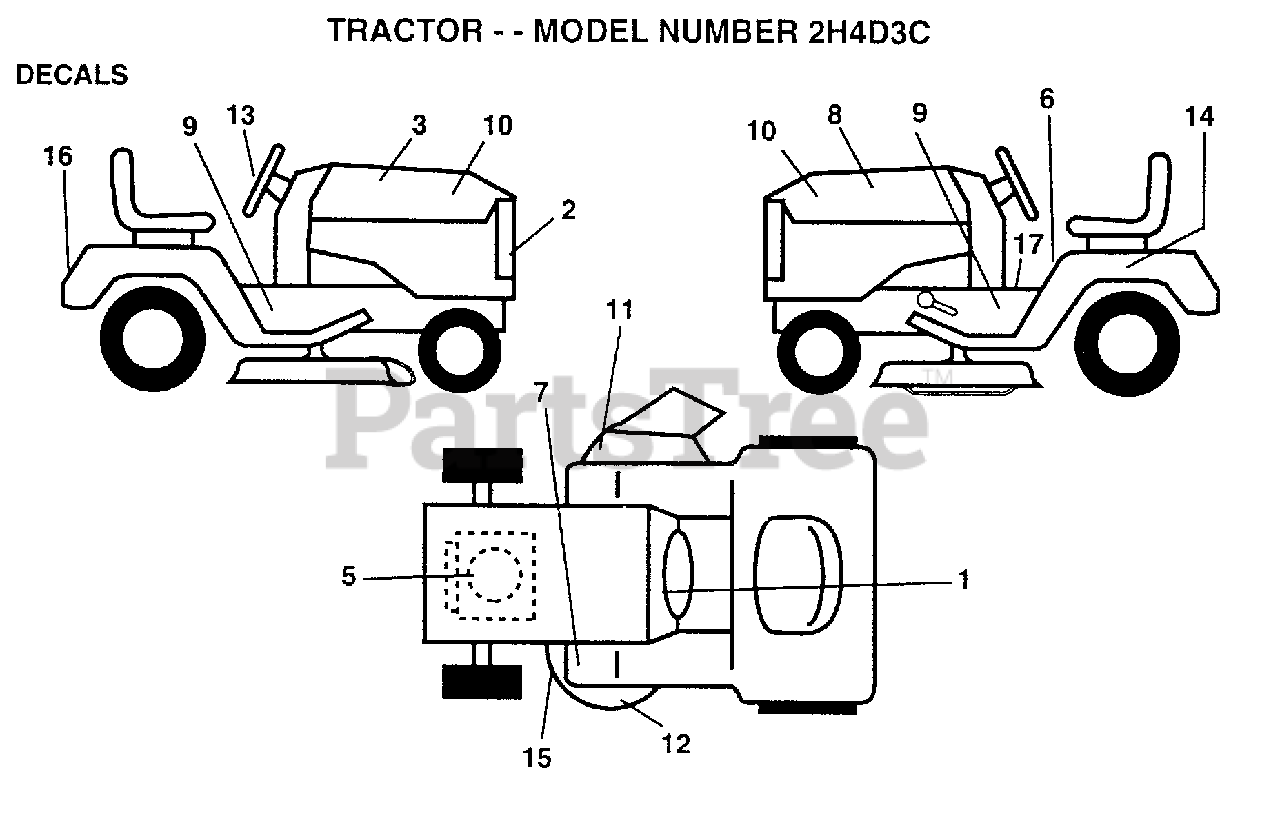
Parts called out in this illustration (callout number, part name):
1	DECAL.DASH.INSTR.
2	GRILL DECAL
3	DECAL.HD.RH.RALLY
5	DECAL, HP ENGINE
6	DECAL CAUTION
7	DECAL T
8	DECAL.HD.LH.RALLY
9	CHASSIS DECAL
11	"DECAL, WARNING"
13	"DECAL,STR WHL"
14	DECAL.BTRY.DANGER
15	DECAL
16	FENDER DECAL
17	DECAL BRAK PARK
